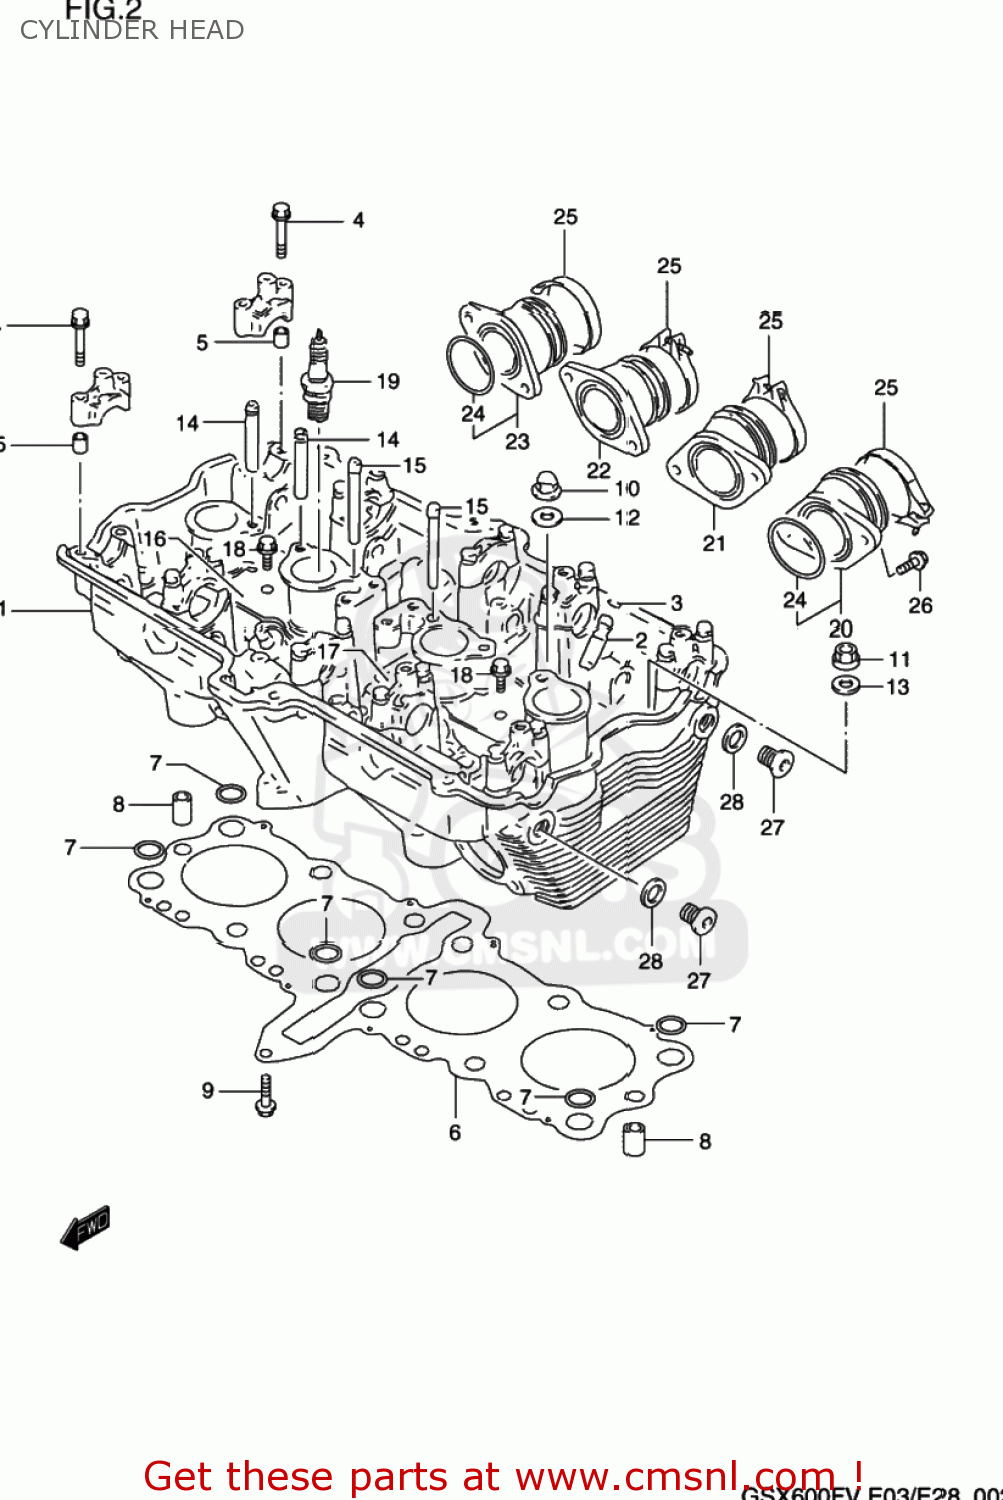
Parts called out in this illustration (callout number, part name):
1	HEAD ASSEMBLY,CYLINDER
2	GUIDE,VALVE
3	RING,SNAP
4	BOLT(6X39)
5	PIN(6.2X8X11)
6	GASKET,CYLINDER HEAD (NAS)
7	O RING(D:2.6,ID:12.1)
8	PIN
9	BOLT
10	NUT
11	NUT
12	GASKET(10.2X20X2).3 (NAS)
13	WASHER (10.5X22X2.3)
14	PIPE,OIL NO.1
15	PIPE,OIL NO.3
16	PLATE,OIL PIPE,R
17	PLATE,OIL PIPE,L
18	BOLT
19	PLUG,SPARK(CR9EK)
20	PIPE ASSY,INTAKE NO.1
21	PIPE ASSY,INTAKE NO.2
22	PIPE ASSY,INTAKE NO.3
23	PIPE ASSY,INTAKE NO.4
24	O RING(D:2.4,ID:39.7)
25	CLAMP
26	SCREW
27	PLUG
28	GASKET(13.8X18.8X4.8) (NAS)
